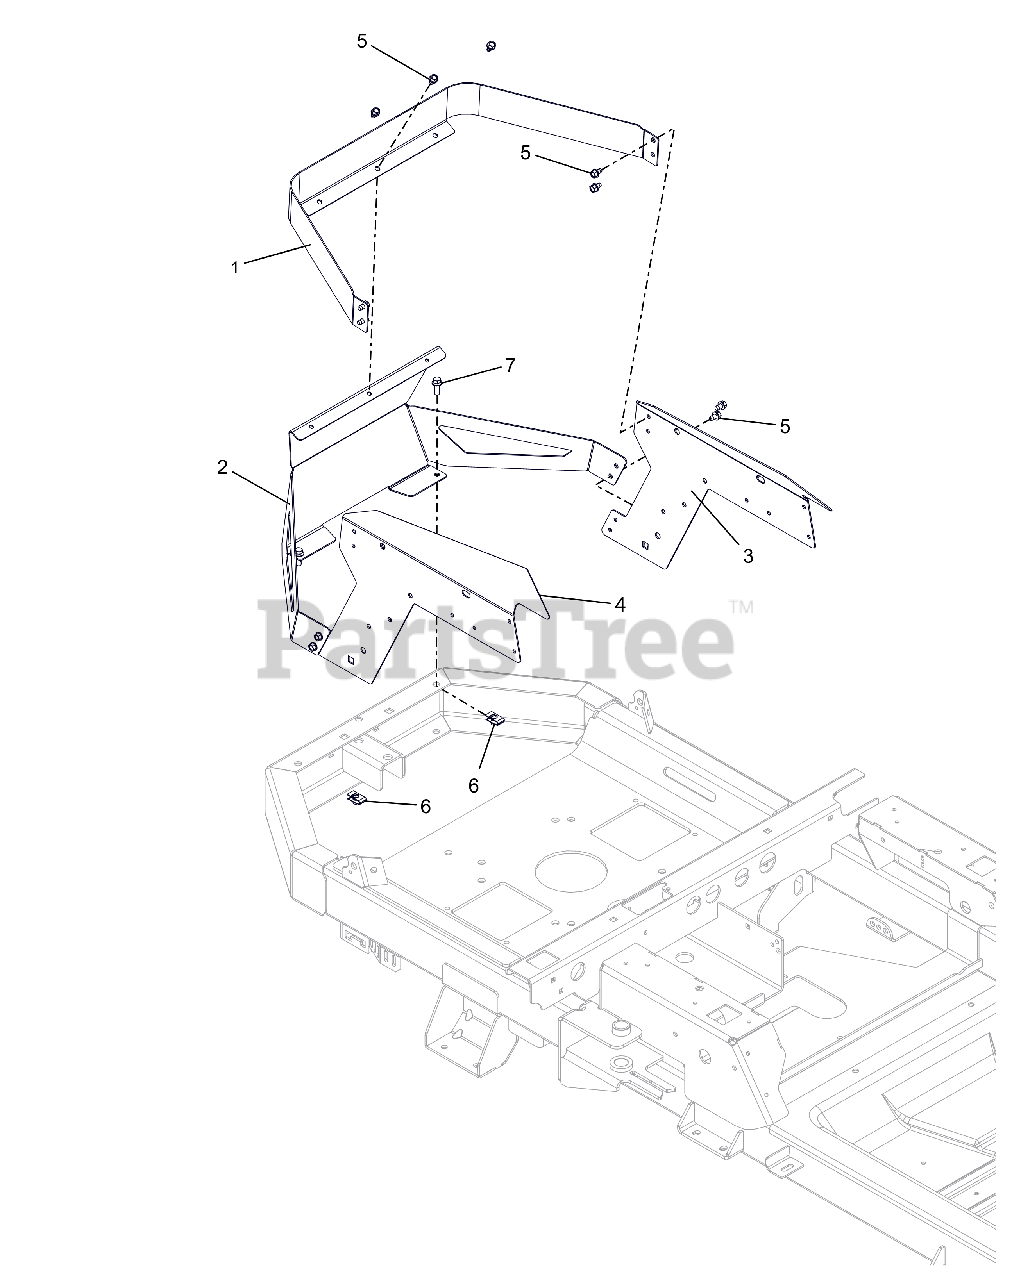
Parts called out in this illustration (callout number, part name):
1	GUARD, ENGINE -TOP TRIM
2	GUARD, ENGINE-BOTTOM BLACK
3	PANEL, LEFT REAR RENDER MOUNT
4	PANEL, RIGHT REAR FENDER MOUNT
5	SCR,TAP .25-20X.375 HWH TR ZCC
6	NUT-RTNR .25-20X.56
7	BLT,HEX-FLG .25-20X.75 G5 BFP
